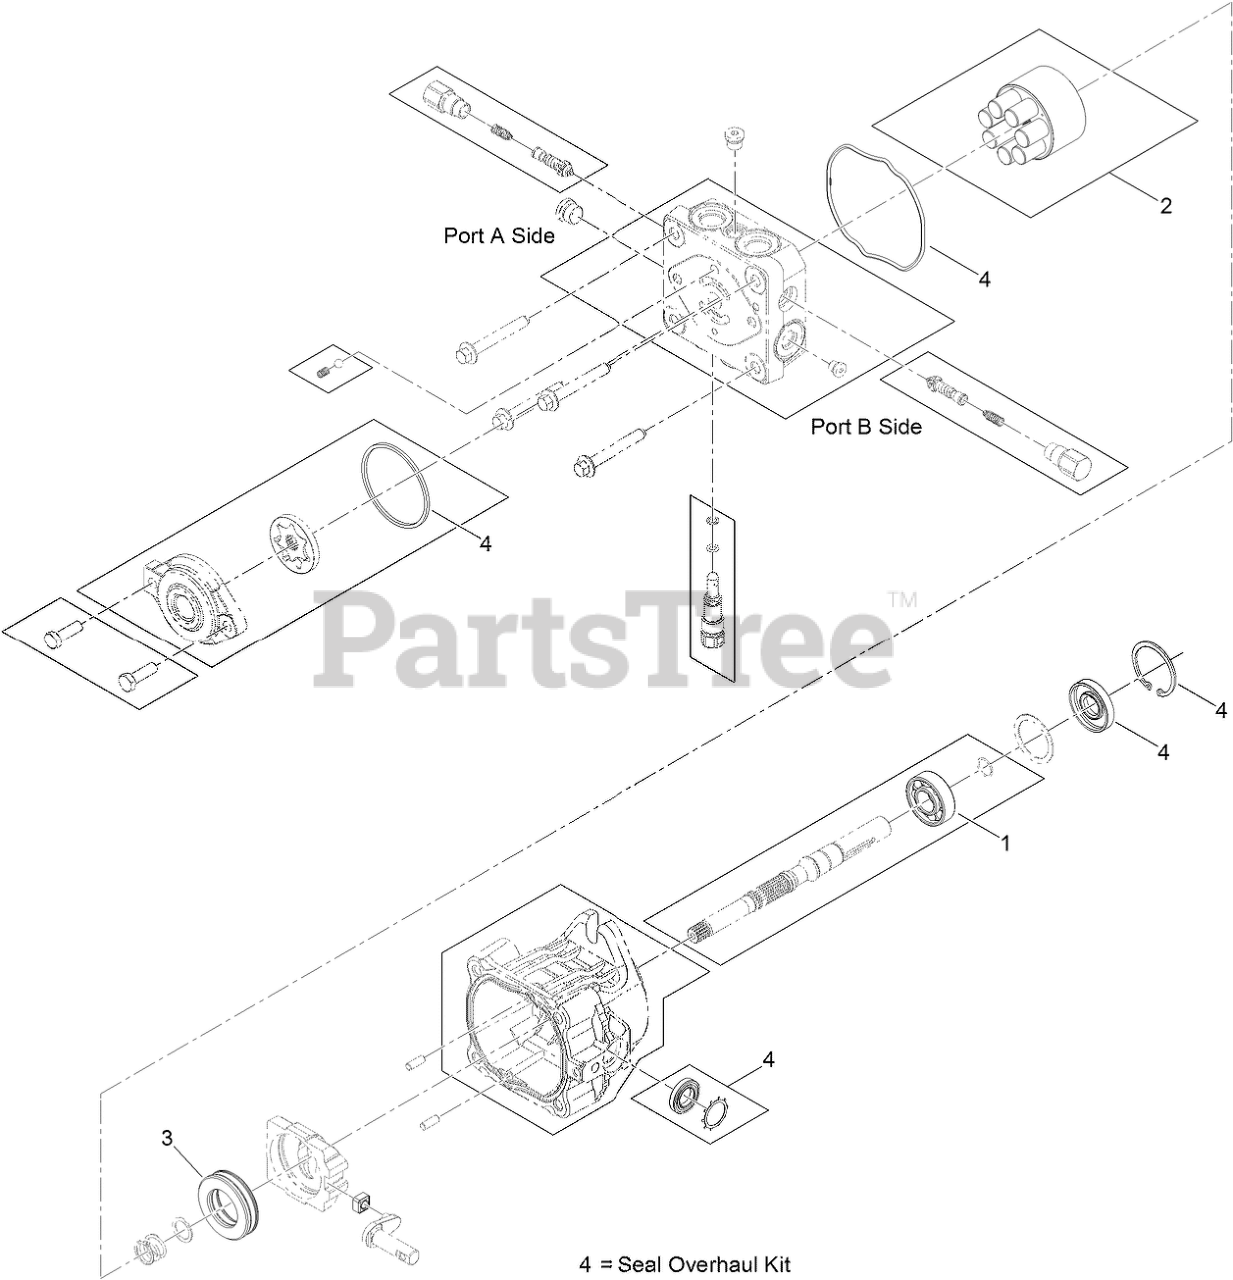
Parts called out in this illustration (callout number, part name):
1	BEARING-BALL
2	CYLINDER BLOCK KIT
3	BEARING-THRUST, PLASTIC C
4	SEAL OVERHAUL KIT
